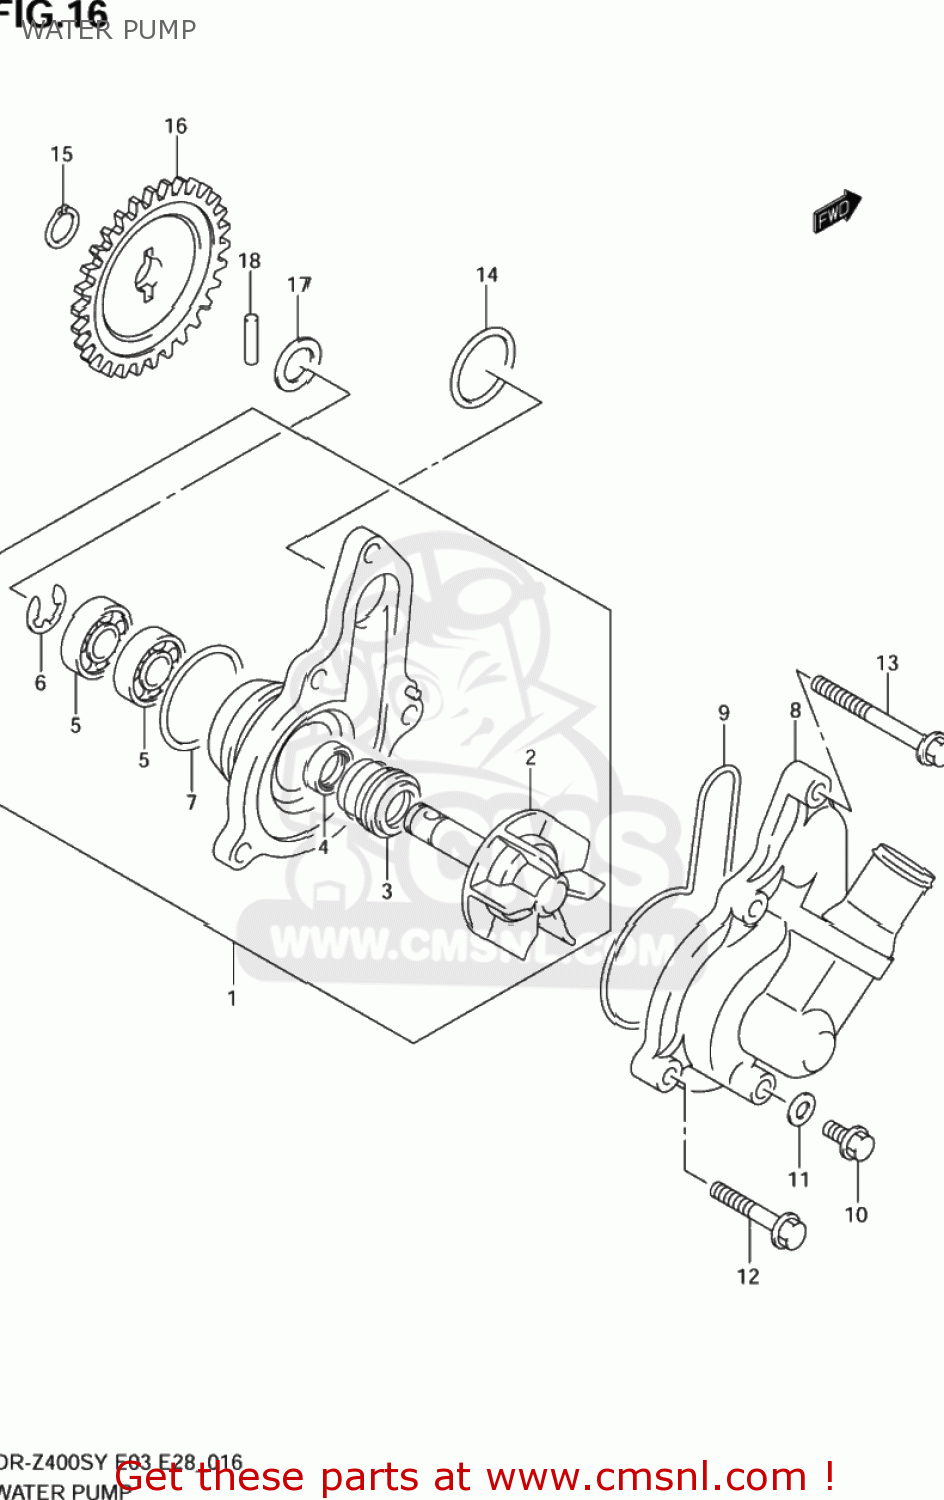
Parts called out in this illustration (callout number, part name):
1	PUMP ASSY,WATER
2	IMPELLER SHAFT
3	SEAL,MECHANICAL
4	SEAL,OIL
5	BEARING
6	E RING
7	O RING,WATER PUMP HOLDER
8	CASE,WATER PUMP
9	O RING,WATER PUMP CASE
10	BOLT
11	GASKET(6.2X11X1).2 (NAS)
12	BOLT(6X30)
13	BOLT(6X45)
14	O RING(D:2.4,ID:21.8)
15	CIRCLIP,10MM
16	GEAR,WATER PUMP DRIVEN
17	SHIM(10X18X0.5)
18	PIN(4X18.5)
